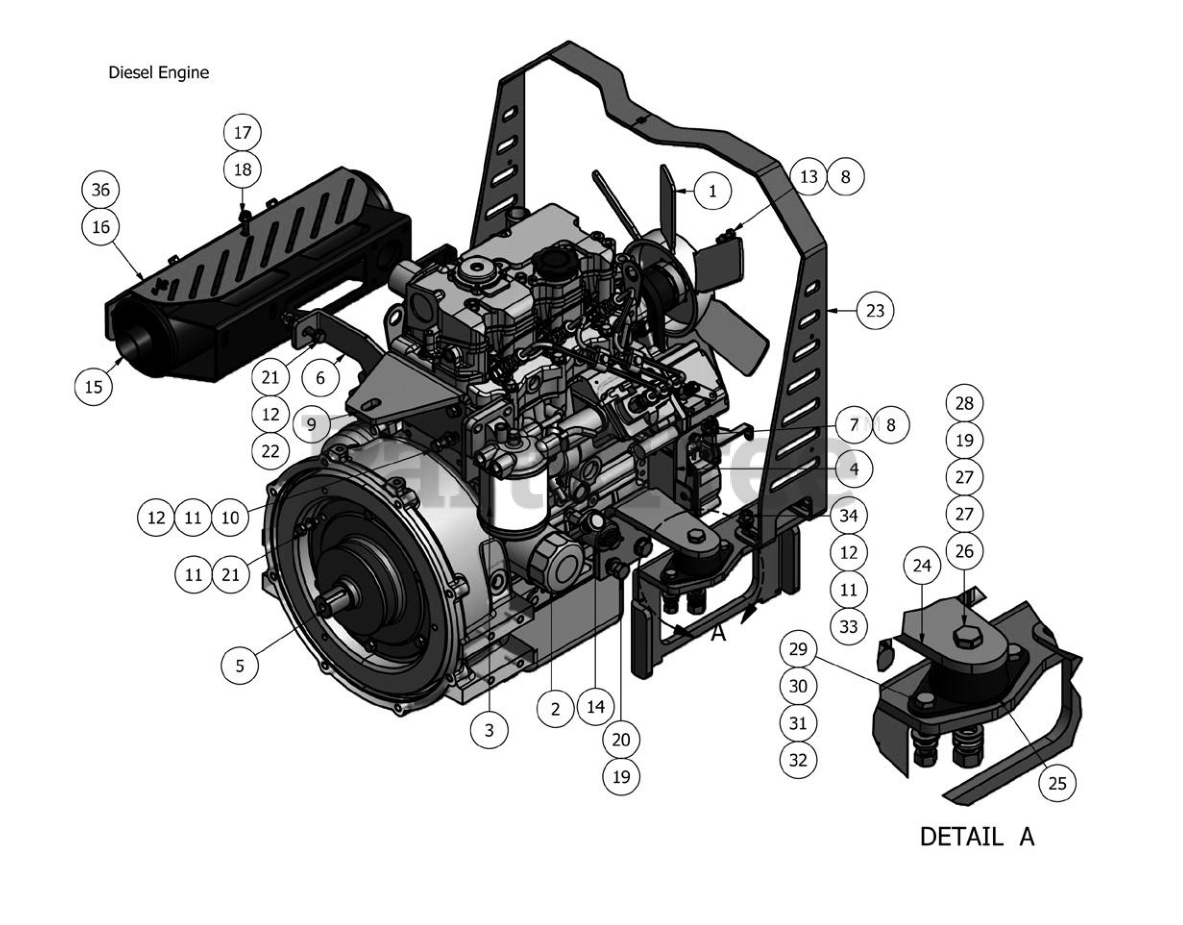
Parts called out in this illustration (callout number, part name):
1	Diesel Fan
2	Cat Oil Filter
3	Fuel Filter
4	Diesel Throttle Bracket (4 Tier)
5	Stub Shaft
6	Diesel Muffler Hanger Bracket
7	6 mm x 10 mm Hex Bolt
8	1/4" Lock Washer
9	Rear Motor Mount for Diesel
10	10-32 x 3/8 Button Head
11	5/16" Lock Washer
12	5/16" Flat Washer
13	6mm x 20mm Bolt
14	Oil Pressure Guage with Sender
15	Diesel Muffler
16	Diesel Muffler Guard (28hp)
17	1/4" x 3/4" Set Screw
18	1/4" Flange Nut
19	1/2" Lock Washer
20	12mm Bolt- Diesel
21	5/16" x 1" Bolt
22	5/16-18 Nylock Flange Nut
23	Hood Holder Diesel
24	Diesel Motor Side Support (Right)
25	Rubber Isolator
26	1/2" x 3" Hex Bolt
27	1/2" Brass Washer
28	1/2" Hex Nut
29	3/8" x 1" Hex Bolt
30	3/8" Flat Washer
31	3/8" Lock Washer
32	3/8" Hex Nut
33	5/16" x 1 1/4" Hex Bolt
35	Diesel Motor Side Support (Left)
36	Diesel Muffler guard 35hp
